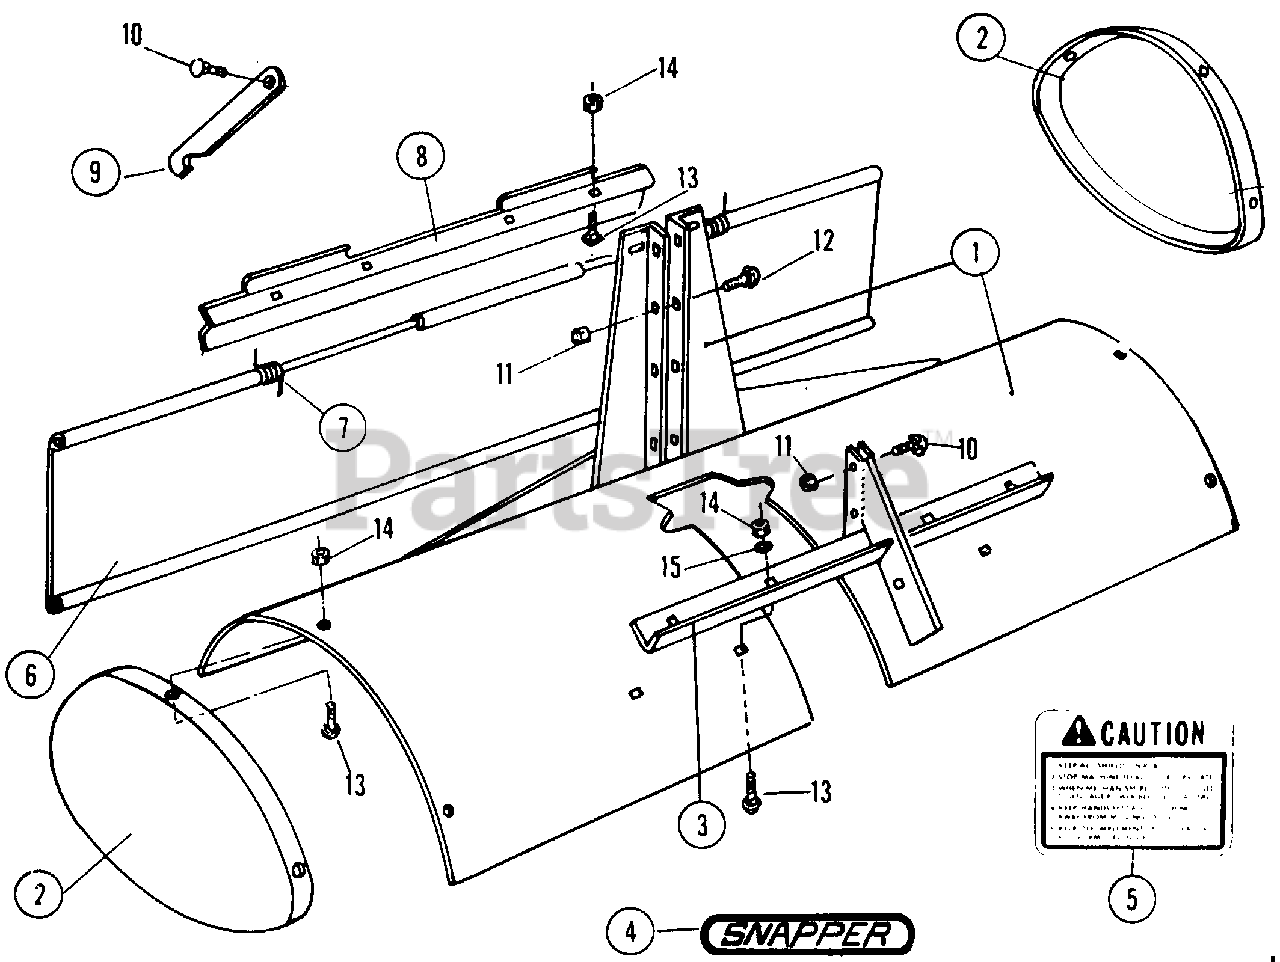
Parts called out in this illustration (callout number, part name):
1	SHROUD ASSEMBLY, 36" TILLER
2	COVER, SHROUD END
3	BRACE, SHROUD
4	DECAL, SNAPPER
5	DECAL, CAUTION
6	LEVEL BLADE
7	SPRING, TENSION
8	HINGE PLATE
9	STRAP, BLADE LOCKING
10	BOLT, 1/4-20 x 1 CARRIAGE
11	LOCKNUT, 1/4-20 HEX
12	BOLT, 1/4-20 x 3/4 CARRIAGE
13	BOLT, 5/16-18 x 1/2 CARRIAGE
14	LOCKNUT, 5/16-18 HEX
15	WASHER, 5/16 PLAIN
